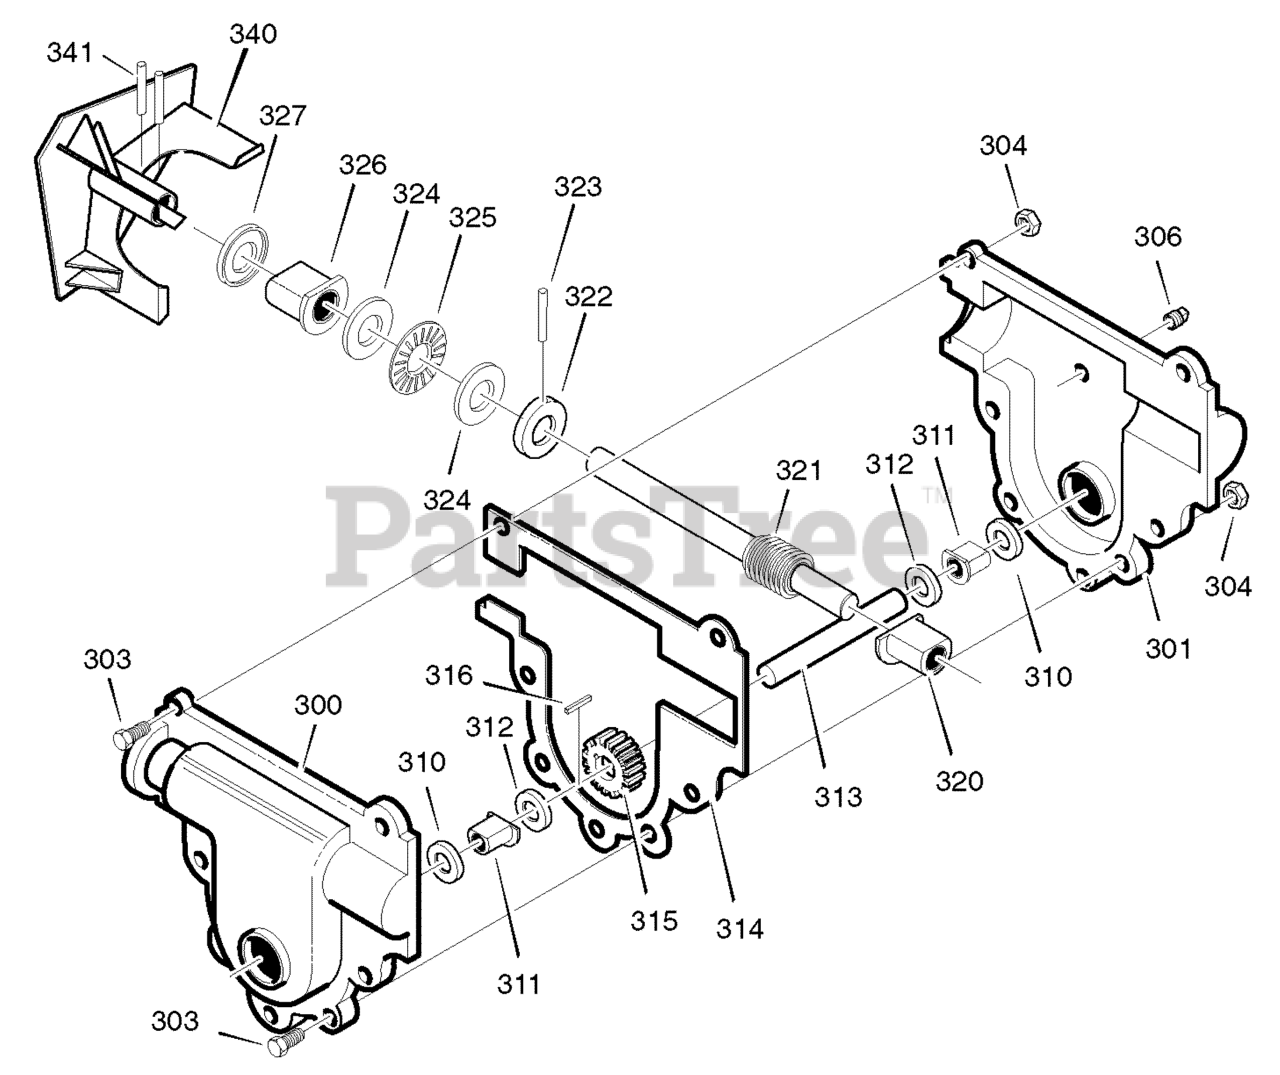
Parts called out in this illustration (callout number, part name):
300	CASE, GEAR, RH
301	CASE, GEAR, LH
304	NUT
306	SCREW
310	SEAL, OIL
311	BEARING, FL
312	WASHER, FLAT
313	SHAFT, OUTPUT
314	GASKET
315	GEAR, WORM
316	KEY, WOODRUFF
320	BRNG, FL
321	SHAFT, INPUT
322	COLLAR, THRUST
323	PIN, SPRING
324	WASHER, FLAT
325	BRNG, ROLL
326	BRNG, FL
327	SEAL, OIL
340	IMPELLER
341	PIN, SPRING
